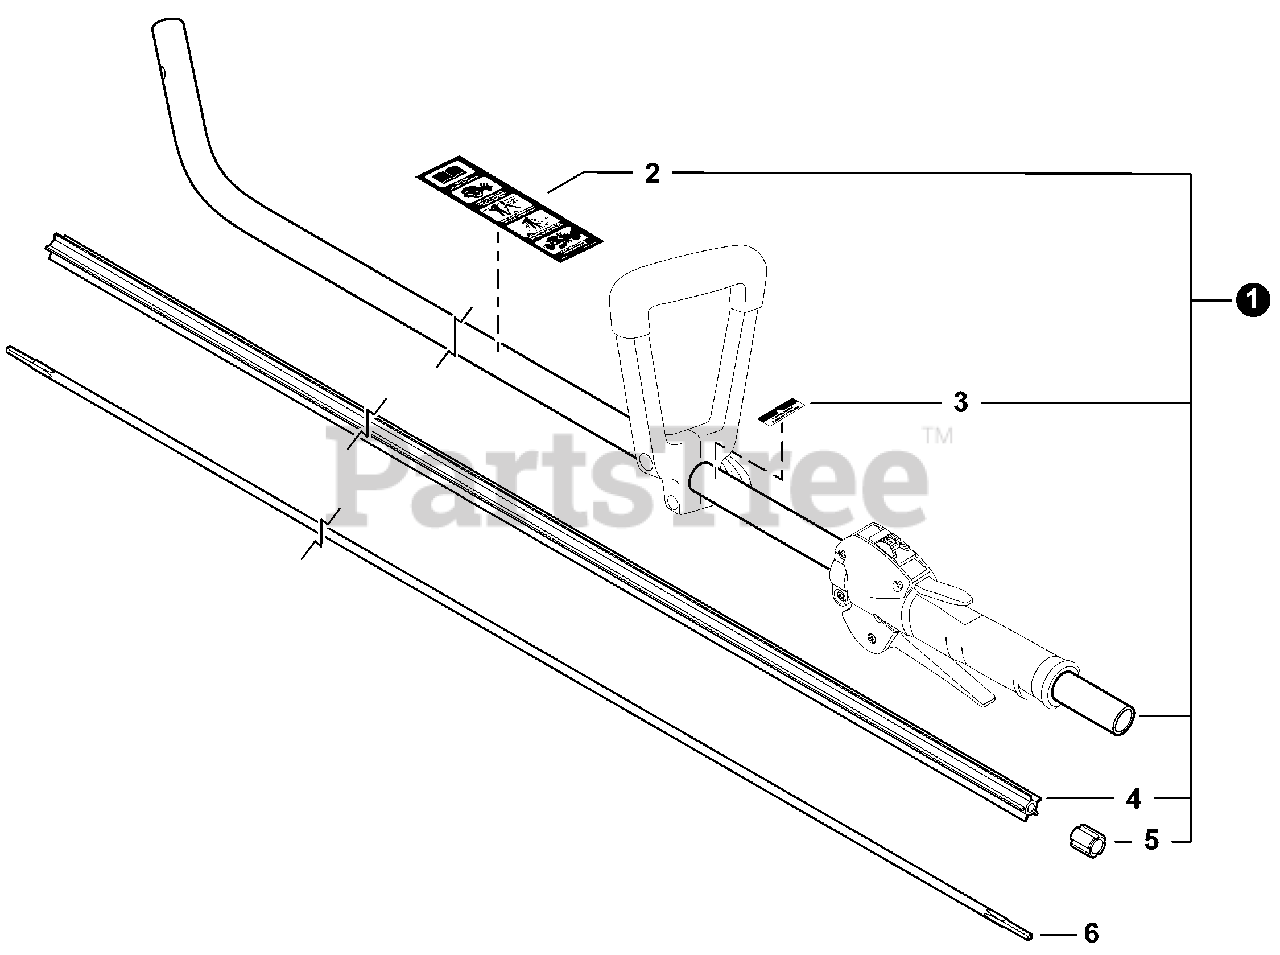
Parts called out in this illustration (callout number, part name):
1	MAIN PIPE ASSY
2	LABEL, CAUTION
3	LABEL, HANDLE
4	LINER, FLEXIBLE 21.6×1420
5	STOPPER
6	DRIVESHAFT - FLEXIBLE
